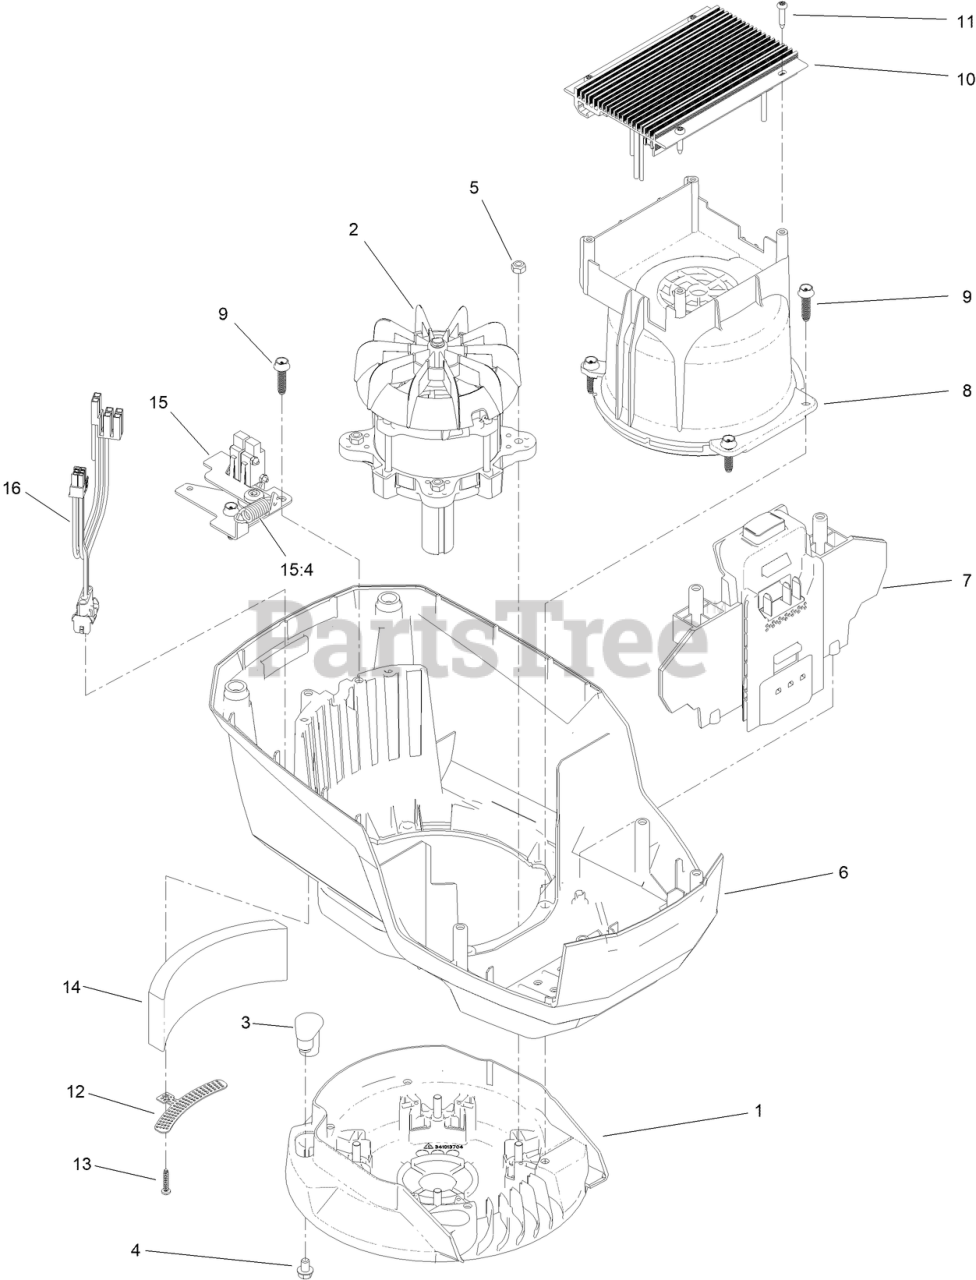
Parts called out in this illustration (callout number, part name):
1	BASE-MOUNT, MOTOR
2	MOTOR-2KW
3	INSERT-MOUNT, Motor
5	NUT-LOCK
6	SHROUD-LOWER
7	BATTERY RECIEVER ASM
8	SHROUD-MOTOR
9	SCREW-FLANGE, PLASTIC
10	CONTROLLER-MOTOR
12	BRACKET-FOAM
13	SCREW-PLASTIC, PPH
15	BAIL SWITCH ASM
15:4	SPRING-EXTENSION
16	HARNESS-WIRE
